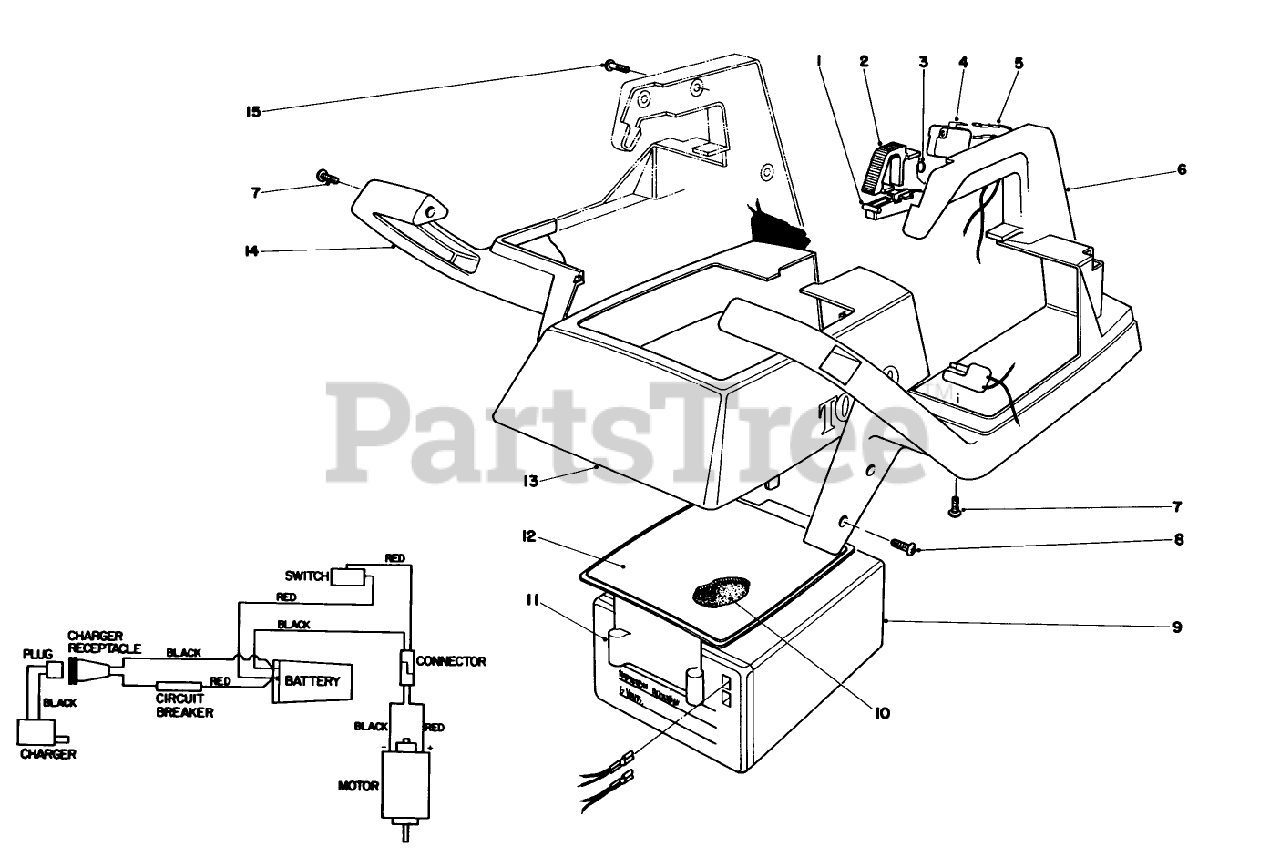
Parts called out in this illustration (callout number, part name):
3	SPRING
6	LH BATTERY CASE/HNDL
8	10-16 X .31 SCREW
